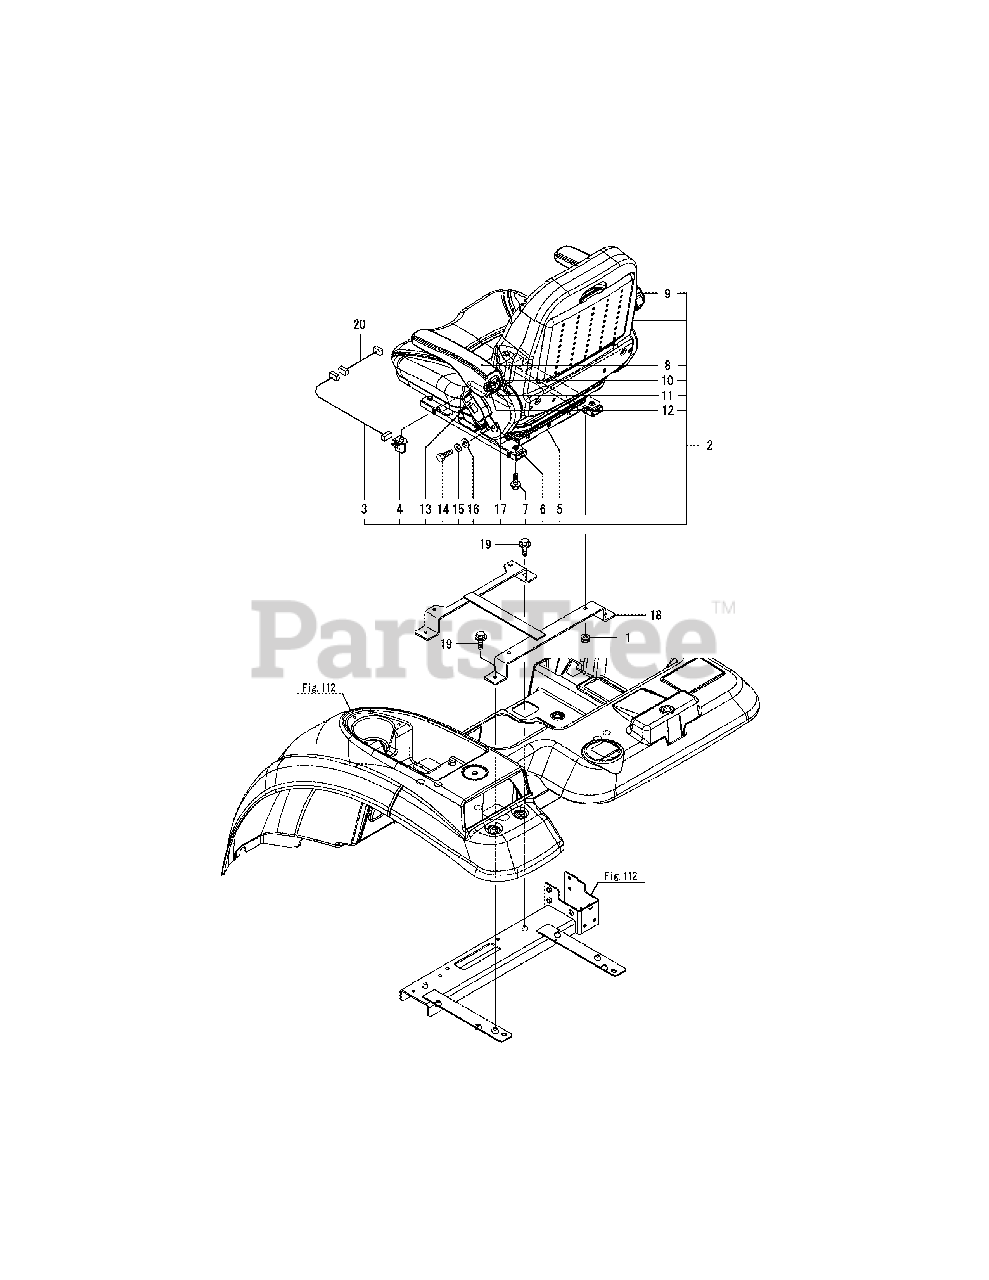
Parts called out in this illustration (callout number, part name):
1	NUT W/WASHER 8
4	SWITCH,SEAT,DELTA,AS
5	SUSPENSION, SEAT
6	SEAT RAIL L/R ASSY
8	ARM REST BODY ASSY L
9	ARM REST BODY ASSY R
11	HEXA HEAD CAP SCREWS
13	SEATBELT ASSY, BELT
18	BRACKET ASSY, SEAT
19	BOLT M 8X 20 PLATED
